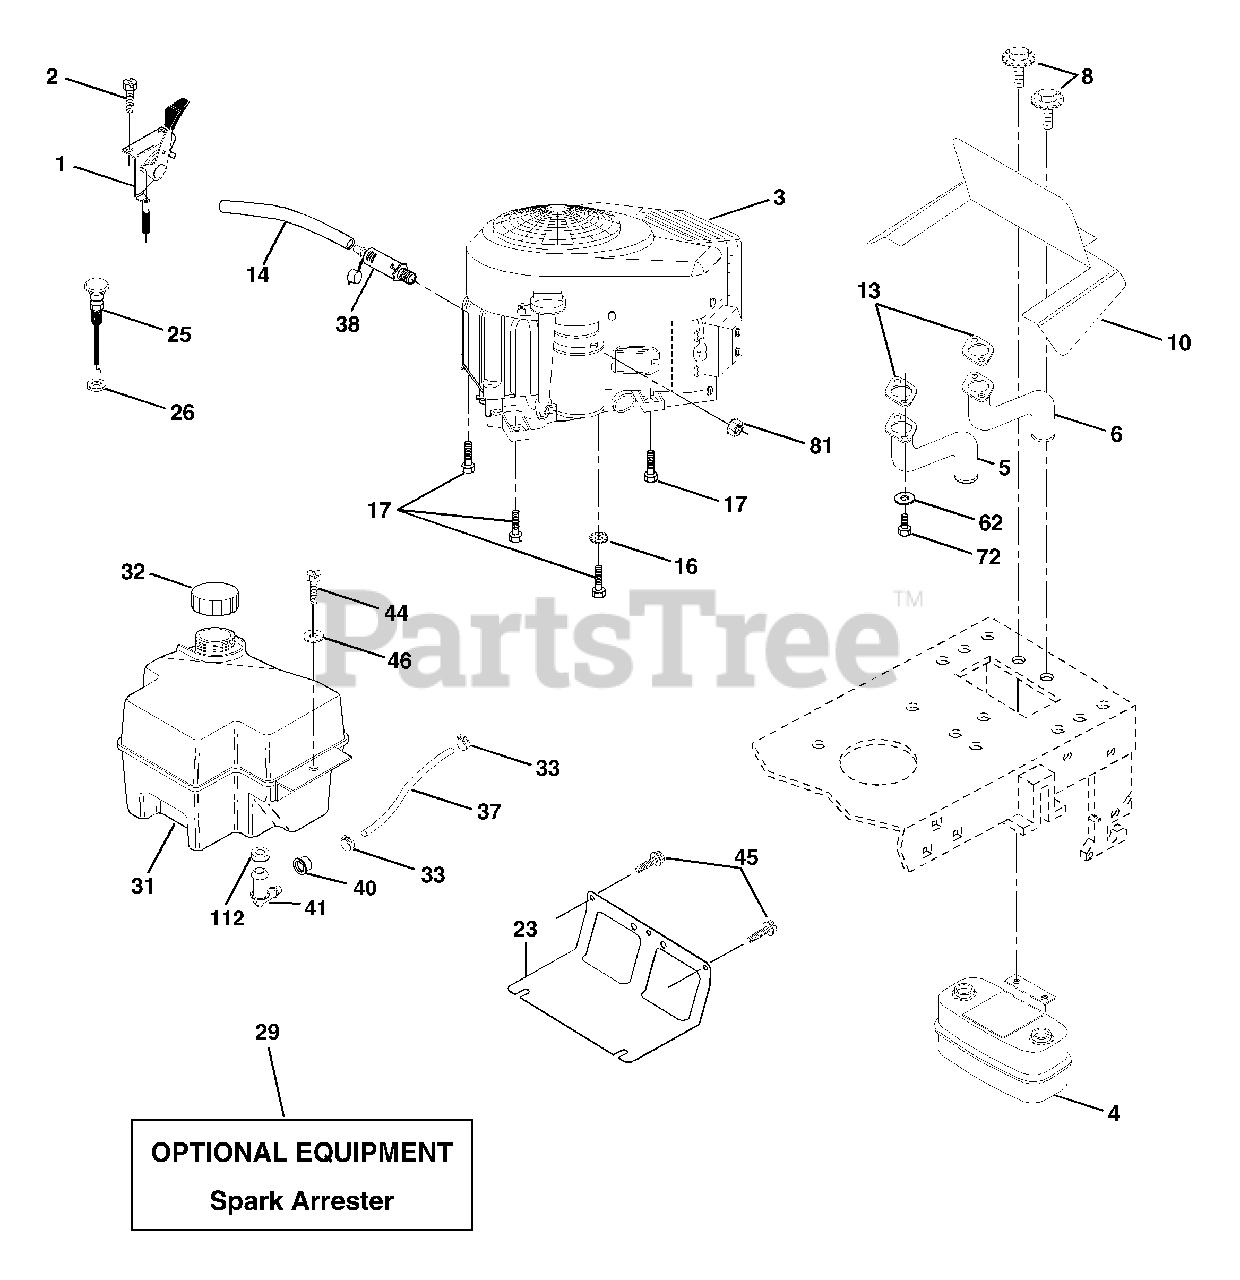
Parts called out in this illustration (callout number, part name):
1	Control Th/ch Flag
2	Screw Hex Thd Cut 1/4-20 x 1/2
4	Muffler
5	Exhaust Tube RH
6	Exhaust Tube LH
8	Bolt 5/16-18 Unc x 3/4 w/Sems Blk
10	Shield Browning
13	Gasket Eng
14	Tube Drain Oil Easy
16	Washer Lock Ext Tooth 3/8
17	Screw 3/8-16 x 1-1/2 SMGML Tap/R
23	Shield Brn/Dbr Guard
25	Control Choke
26	Nut Keps 3/8-24 Unf
29	Kit Spark Arrestor (Flat Scrn)
31	Tank Fuel Front
32	Cap Asm Fuel W/sym Vented
33	Clamp Hose Black
37	Line Fuel 20"
38	Plug Drain Oil Easy
40	Bushing Snap Nyl Blk Fuel Line
41	Stem Tank Fuel
44	Screw Hexwsh Thdrol 1/4-20x3/4
45	Screw Hexwsh Thdr 3/8-16 x 3/4
46	Washer 9/32 X 7/8 X 16 Ga
62	Washer Lock Hvy Hlcl Spr 5/16
72	Screw Hex Hd Cap 5/16-18 x 3/4
81	Nut Keps Hex 1/4-20 UNC
112	Bushing
